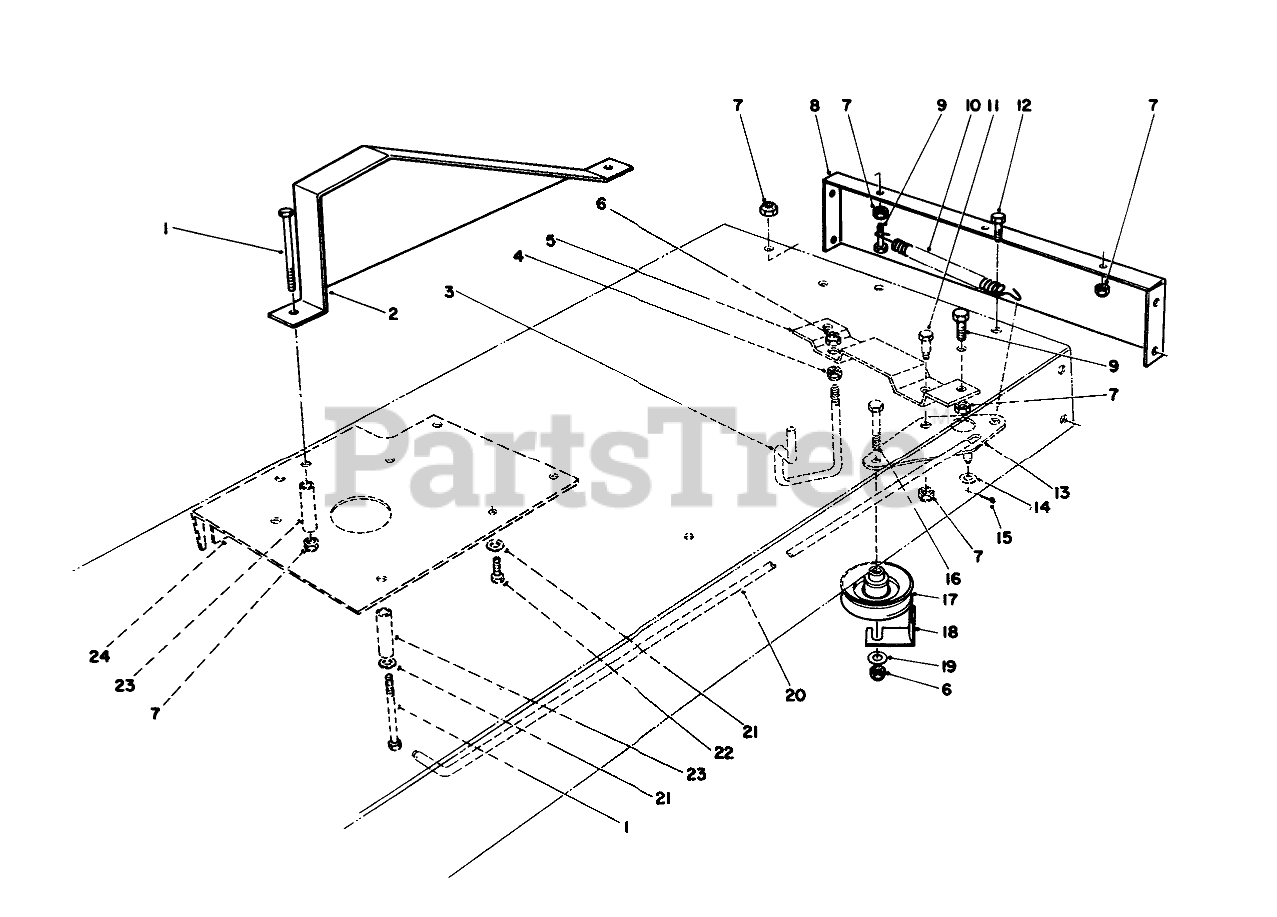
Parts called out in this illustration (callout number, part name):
1	SCREW-HH
2	CHAIN GUARD R
3	BELT GUIDE
4	NUT-LOCK, SIDE
5	TRACT SUPP BRKT B
6	NUT-LOCK, CONE
7	NUT-LOCK, NI
8	REAR FRAME R
9	SCREW-HH
10	TRACTION SPRING
11	BOLT-SHOULDER
12	SCREW-HH
13	TRACTION PIVOT BRKT
14	WASHER-FLAT
15	PIN-COTTER
16	SCREW-HH
17	PULLEY-IDLER
18	RETAINER-BELT
19	WASHER-FLAT
20	TRACTION ROD
21	WASHER-PLAIN
22	Screw-HH
23	OUTER TUBE SPACER
24	REINF PLATE R
